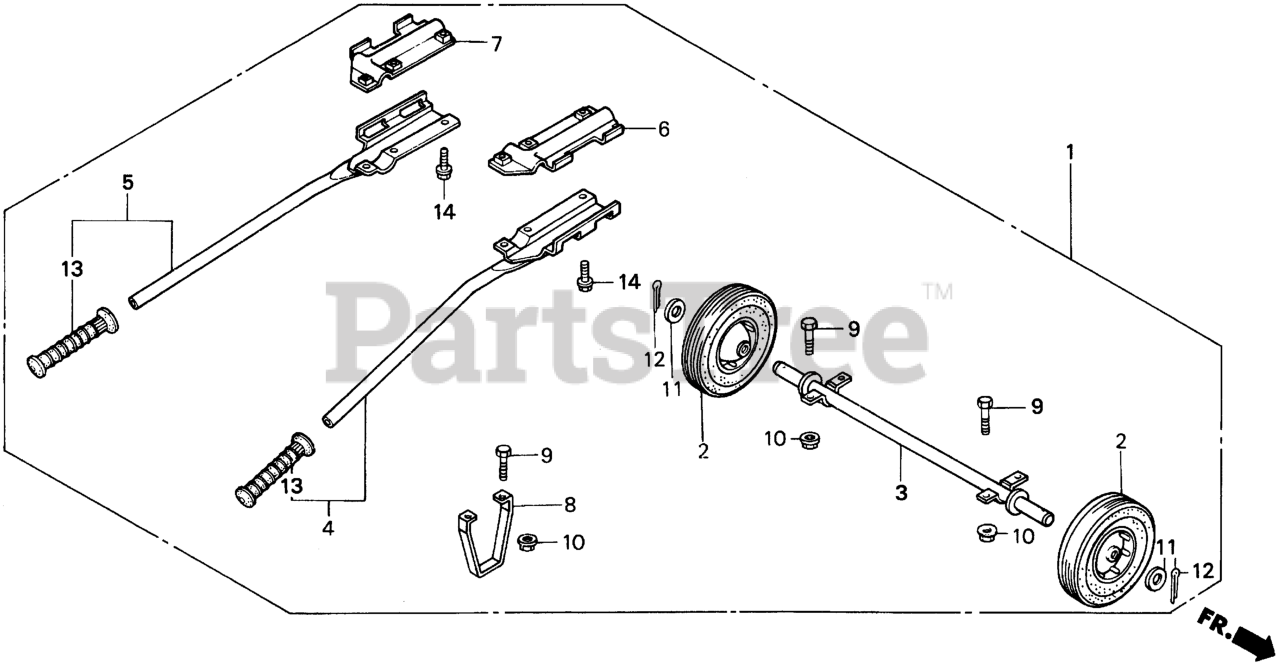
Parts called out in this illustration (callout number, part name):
1	WHEEL KIT (2-WHEELS)
2	WHEEL (GLEASON 10"X2.75"=254X70)
3	SHAFT, WHEEL
4	HANDLE, R. (LOWER)
5	HANDLE, L. (LOWER)
6	BRACKET, R. HANDLE (UPPER)
7	BRACKET, L. HANDLE (UPPER)
8	STAND
9	BOLT, HEX. (8X16)
10	NUT, FLANGE (8MM)
11	WASHER, PLAIN (20MM)
12	PIN, SPLIT (4.0X28)
12	PIN, COTTER (4.0X30)
13	GRIP D, R. HANDLE (BOTH SIDES)
14	BOLT, FLANGE (8X16) Use from Engine SN 1000016.
